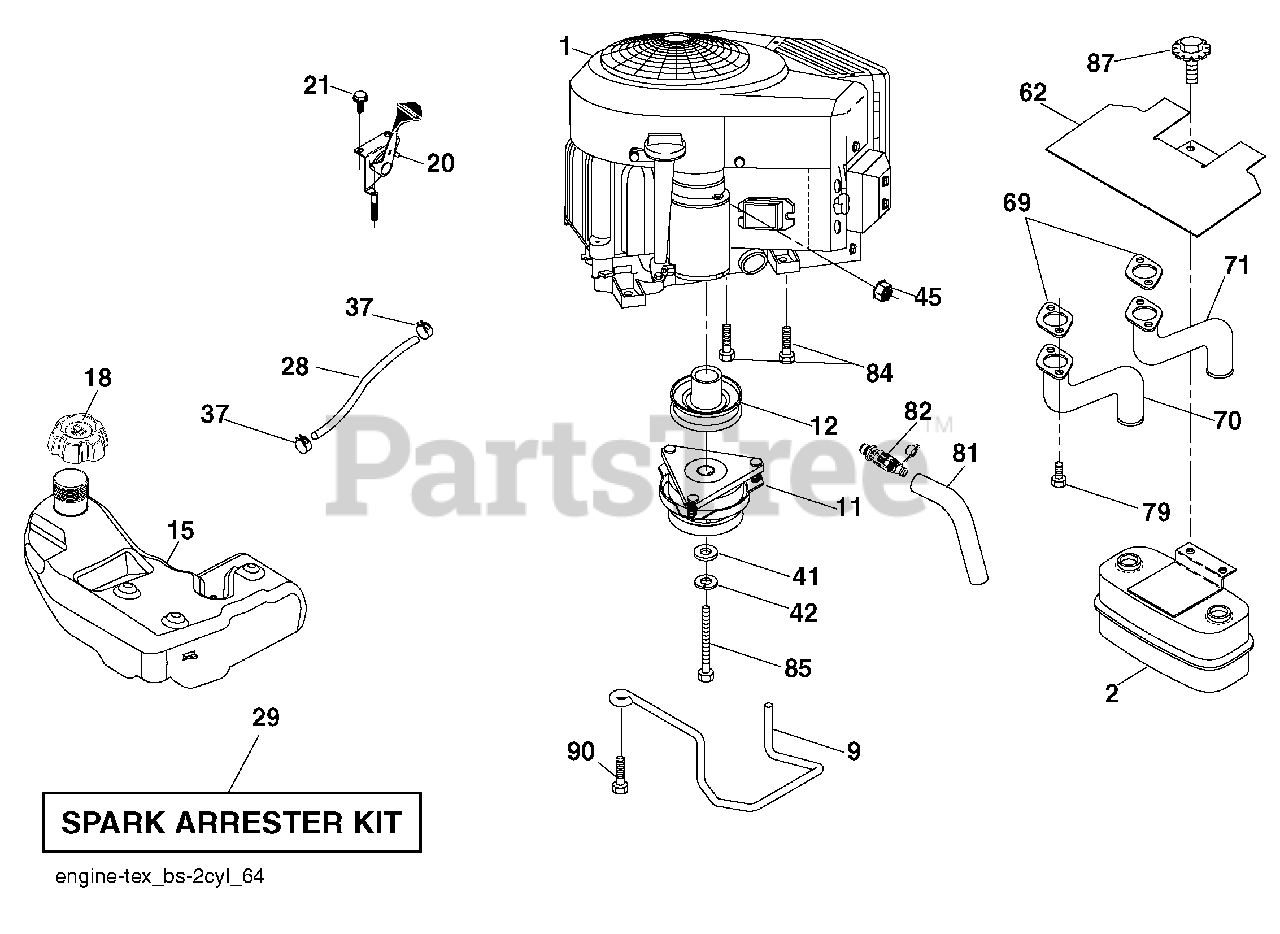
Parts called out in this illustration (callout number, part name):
9	Keeper Belt Engine
11	Clutch Ogura
12	Pulley Engine
15	Tank Fuel
18	Cap
20	Control Throttle
21	Screw #10 x 0.750 BOS Thread
28	Fuel Line
29	Spark Arrester Kit
37	Clamp Hose
41	Washer 1-1/2 OD x 15/32 ID x .250
42	Washer Lock 7/16
45	Nut Keps Hex 1/4-20 unc
62	Shield Heat Muffler
70	Exhaust Tube LH
71	Exhaust Tube RH
79	Screw Socket Head 5/16-18 x 1
81	Tube Drain Oil Easy
82	Plug Drain Oil
84	Screw 3/8-16 x 1-1/4
85	Bolt 7/16-20 x 4
87	Bolt 5/16-18 x 3/4
90	Screw 3/8-16 x 1
